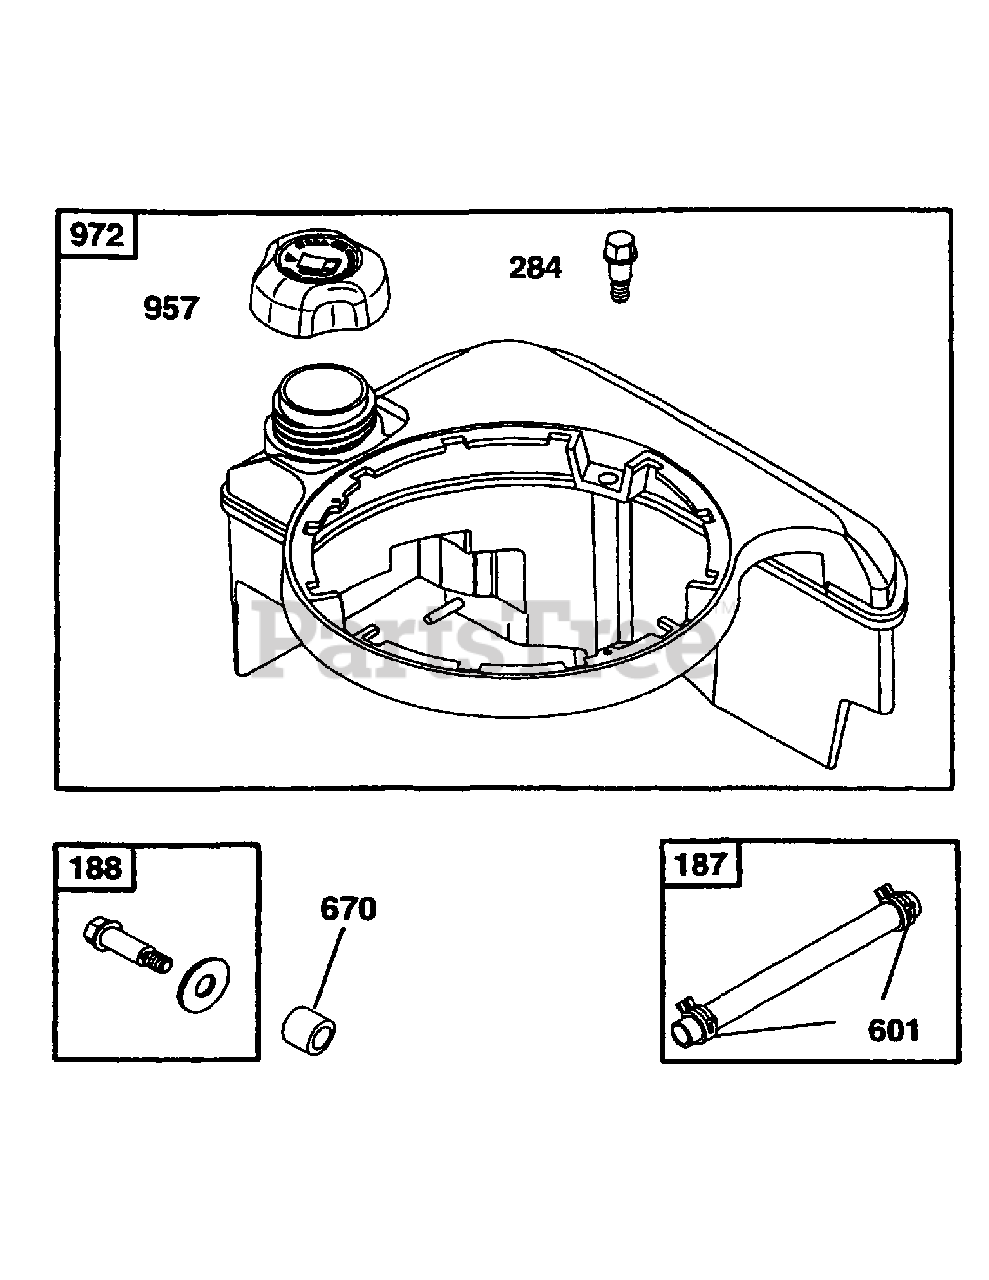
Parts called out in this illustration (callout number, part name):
187	Fuel line
188	Shoulder Screw
284	Shoulder Screw
601	Hose Clamp
670	Fuel Tank Spacer
957	Fuel Tank Cap
972	Fuel Tank
